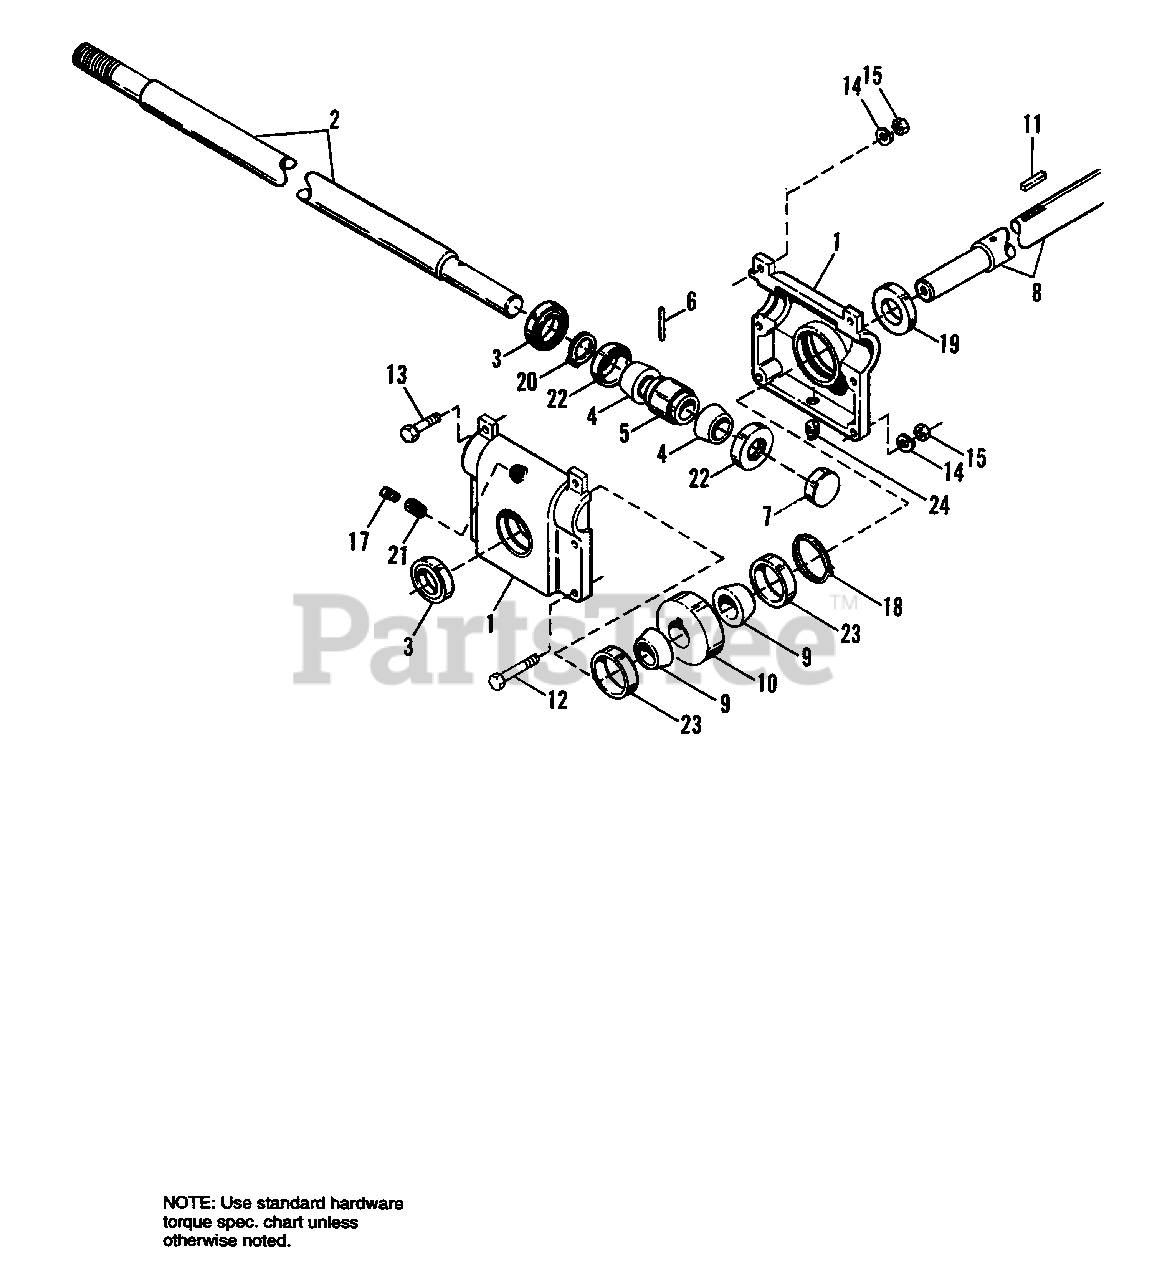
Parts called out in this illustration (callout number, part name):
1	CASE, Gearbox
2	SHAFT, Input
4	BEARING, Roller
6	PIN, Dowel, 1/4 x 1-1/8
7	PLUG,2" Dia. x 11/32
8	SHAFT, Output
9	BEARING, Roller
11	KEY, 1/4 x 1/4 x 5/8
12	CAPSCREW, Hex Hd., 5/16-18 x 2-1/2
13	CAPSCREW, Hex Hd. 5/16-18 x 1-1/4
14	LOCKWASHER, 5/16 Regular
15	NUT, Hex, 5/16-18
16	PLUG, Pipe, Sq. Solid Hd. 1/4 NPT
17	BRACKET, Support
18	RING, Retaining
19	SEAL, Oil, 1.0 ID x 2.0 OD
20	RING, Retaining
21	BUSHING, 1/4 male x 1/8 female
22	RACE, Bearing
23	RACE, Bearing, 1-31/32 OD x 3/8 W
24	VENT, Relief
